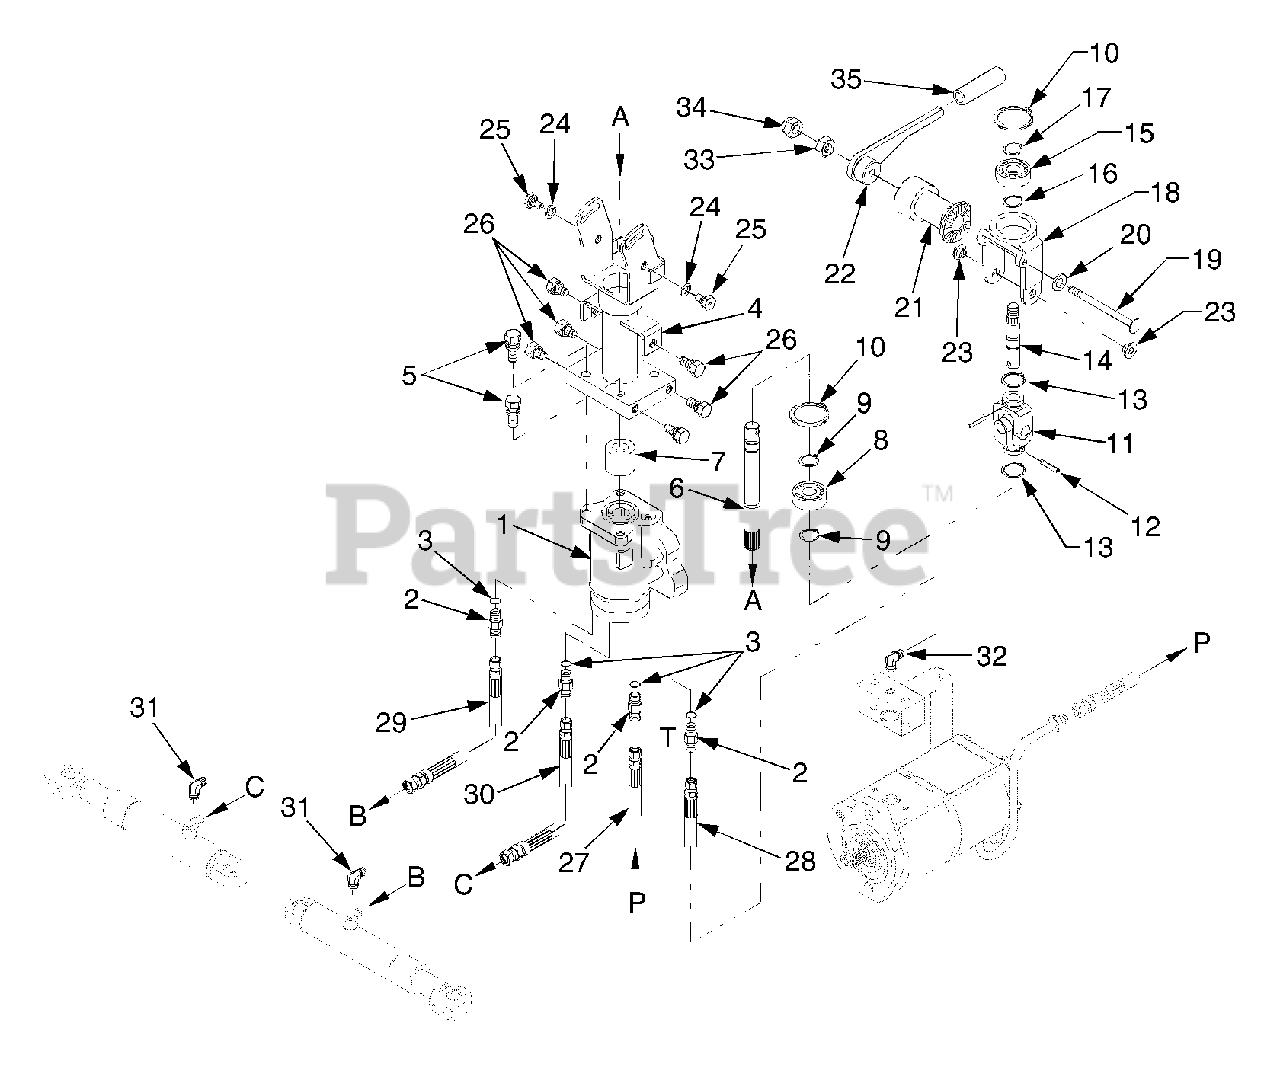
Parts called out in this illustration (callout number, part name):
1	Unit, Power Steering
6	Shaft, Steering
8	Bearing, Ball
11	Joint, Universal
14	Shaft, Connector
15	Bearing, Ball
20	Washer 1, Lock
21	Washer 2, Lock
24	Washer, Spring
27	Steering Hose (P) Ass'y
28	Steering Hose (T) Ass'y
29	Steering Hose (L) Ass'y
30	Steering Hose (R) Ass'y
31	Elbow, 45
32	Adapter 1,cylinder
35	Grip
